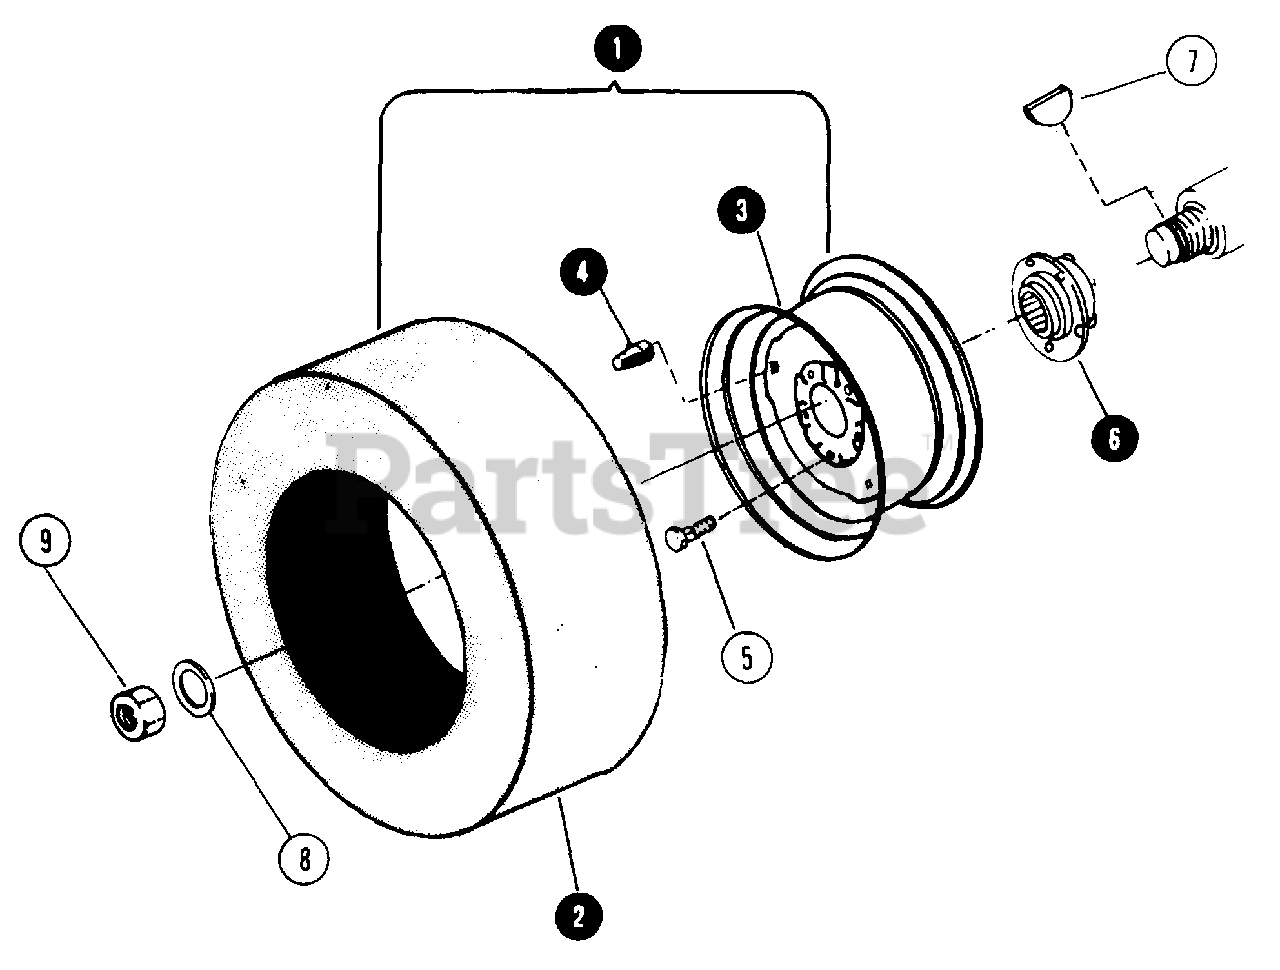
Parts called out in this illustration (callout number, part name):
1	WHEEL ASSEMBLY
2	TIRE,
3	RIM,
4	VALVE, AIR
5	BOLT, REAR WHEEL TO HUB
6	HUB, REAR WHEEL
7	KEY, 1/4 x 1 -1/8
8	WASHER, FLAT 1-1/8
9	NUT, HEX JAM l-1/8
